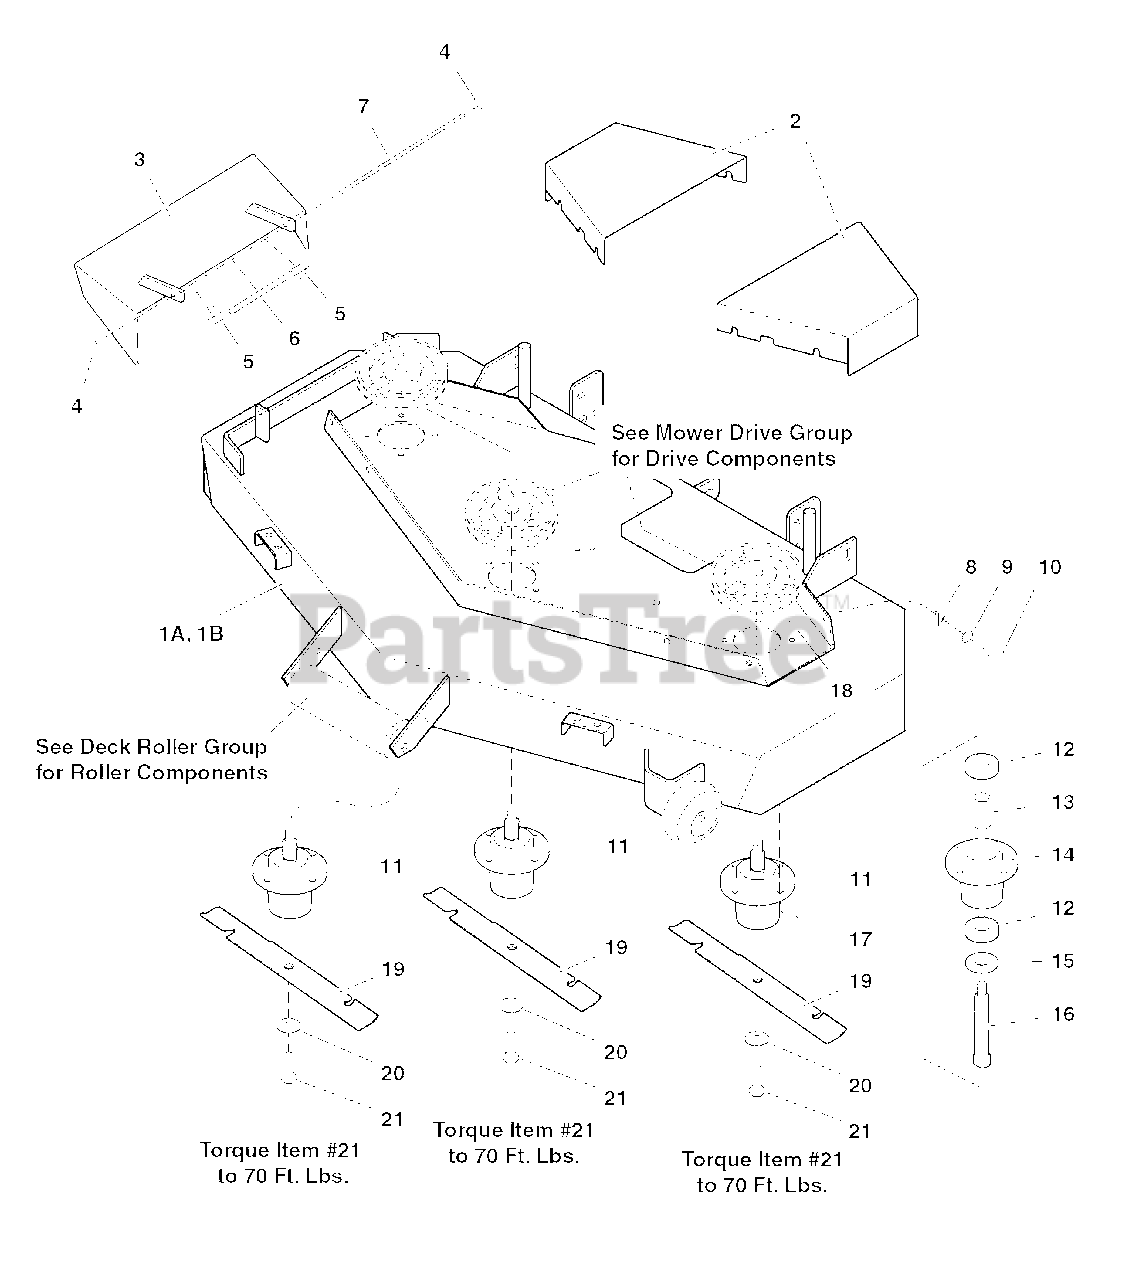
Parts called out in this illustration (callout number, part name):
1	48" MOWER DECK
2	MOWER DECK GUARD
3	DISCHARGE CHUTE
4	NUT, Hex, Nylon Lock, 5/16-18
5	SPRING, Torsion
6	SPRING SPACER
8	BODY CLIP, 5/16-18
9	WASHER, 5/16
10	CAPSCREW, Hex Hd, 5/16-18 x 3/4
11	SPINDLE ASSEMBLY, Complete (includes Ref 10-14)
12	BEARING, Roller
13	SPACER, Bearing
14	SPINDLE HOUSING
15	TRASH SHIELD
16	SPINDLE SHAFT
17	CAPSCREW, Hex Hd, 5/16-18 x 1-1/8
18	NUT, Hex, Serrated Flange, 5/16-18
19	MOWER BLADE (48" Deck)
20	WASHER, USS, 5/8
21	CAPSCREW, Hex Hd, 5/8-11 x 1-3/4-
